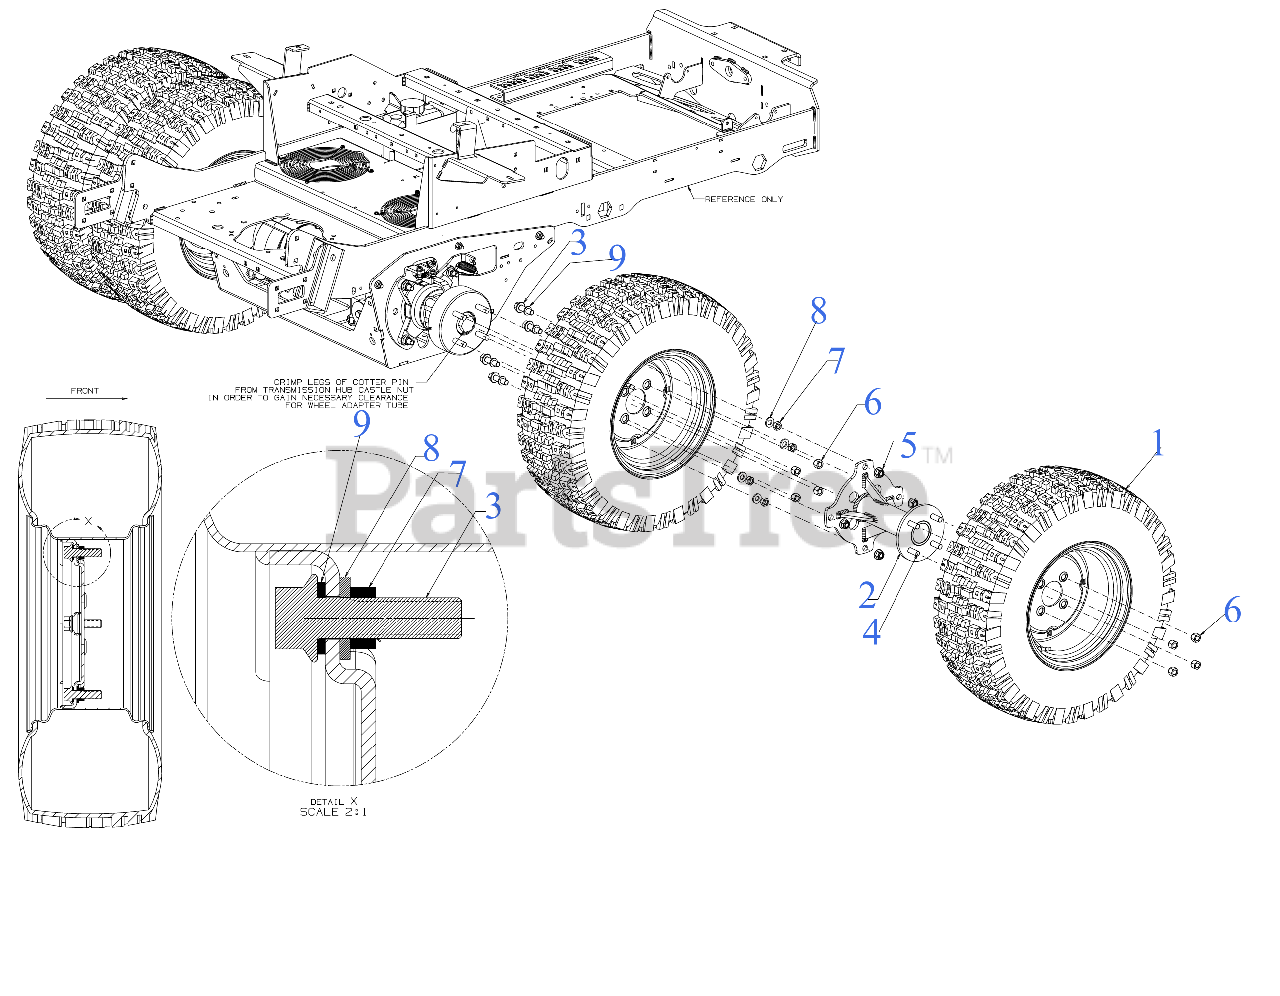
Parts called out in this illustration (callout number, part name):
1	WHEEL ASSEMBLY (25 x 9-12) (KENDA)
1	TIRE (25x9x12)
2	DUAL WHEEL ADAPTER ASSEMBLY
3	FLANGE BOLT 1/2-13:1.75:GR5
4	RIBBED NECK STUD
7	HEX JAM NUT 1/2-13
8	FLAT WASHER
9	FLAT WASHER
